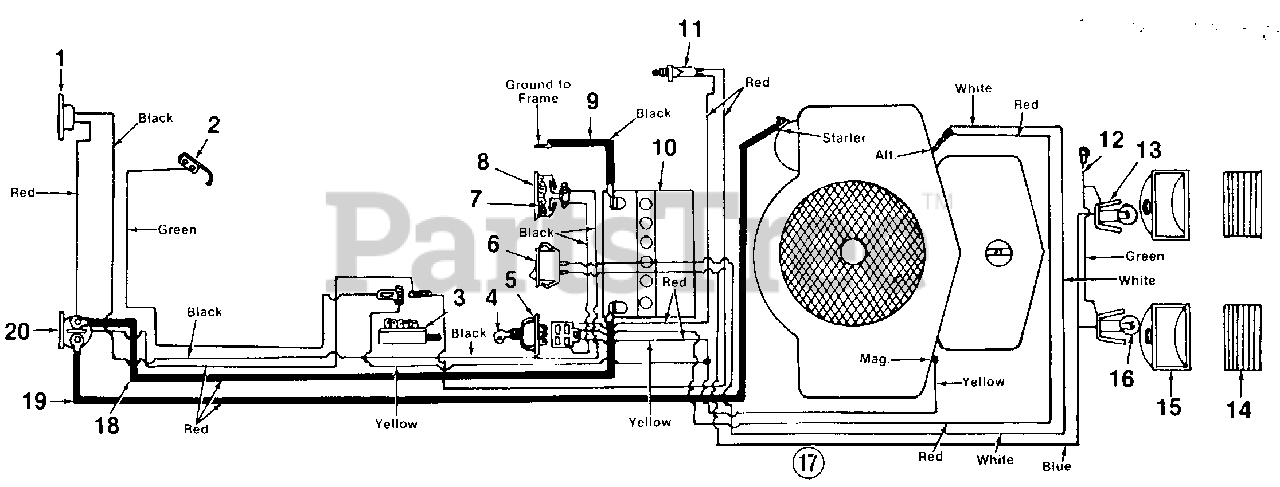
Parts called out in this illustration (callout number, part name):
1	Circuit Breaker
2	Spring Switch
3	Safety Switch Dpst.
4	Ignition Key
5	Ignition Switch
6	H ead I i g ht Sw i tc h
7	Foam Strip
8	Ammeter
9	Ground Wire 14.0" Lg.
10	12 Volt Battery
11	Safety Switch
12	Ground Wire
13	Socket
14	Lens
15	Headlight Housing
16	Lamp
17	Wire Harness
18	Electric Wire 27.0" Lg.
19	Electric Wire 32.5" Lg.
20	Solenoid
